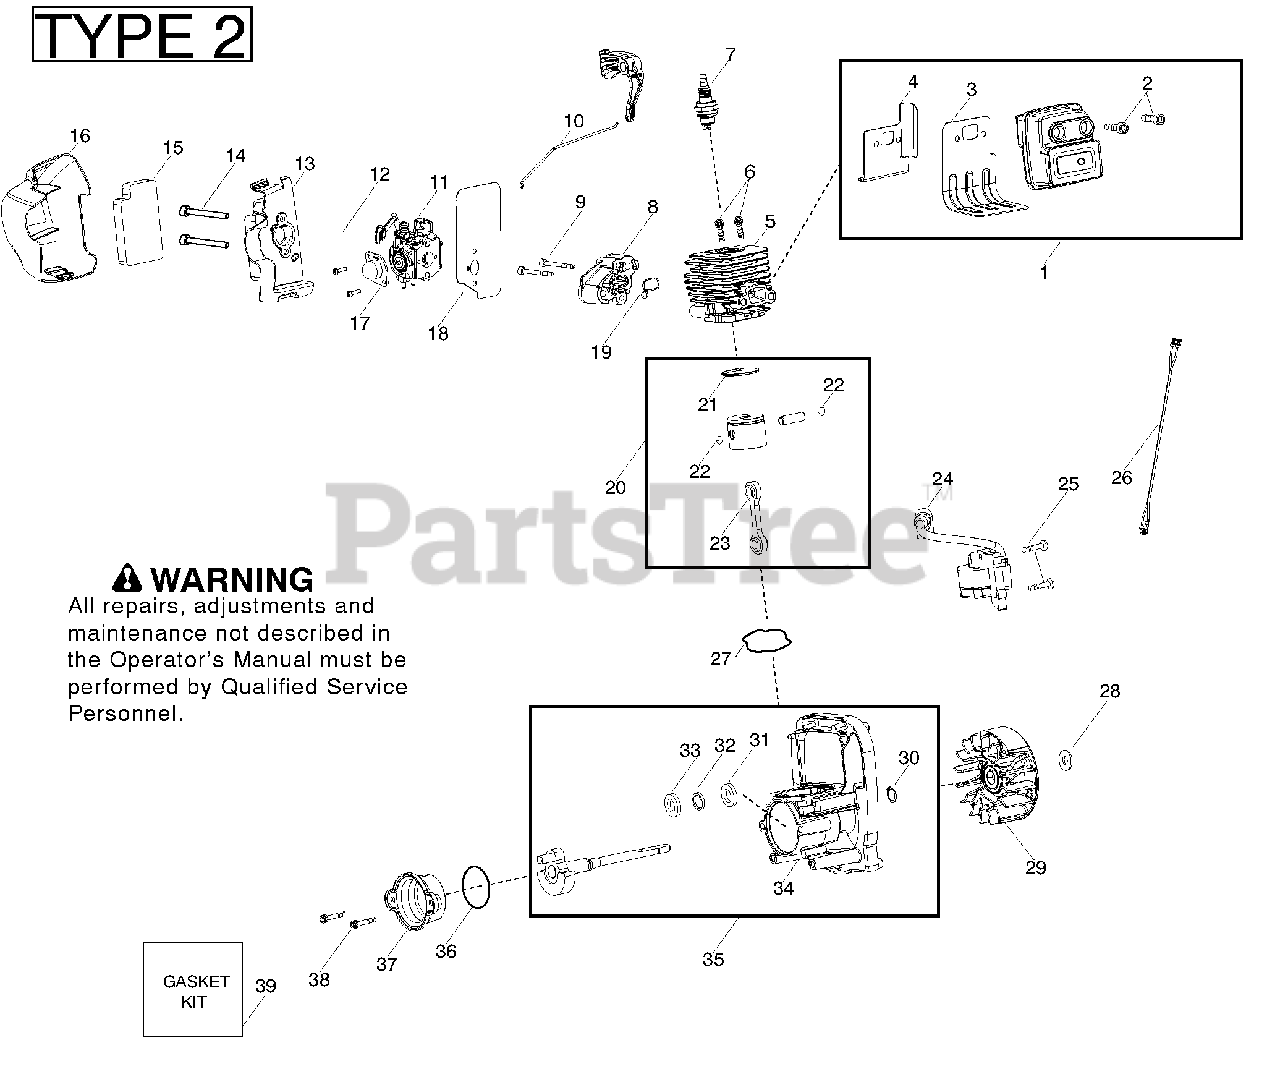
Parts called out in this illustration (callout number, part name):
1	Assy - Muffler
3	Gasket-Muffler (gasket kit)
4	Shield - Muffler Heat
5	Cylinder
7	Spark Plug (RCJ-6Y)
8	Adapter - Carb.
10	Linkage - Throttle
11	Kit - Carb. Assy (WT847)
12	Lever- Choke, (Gold)
12	Lever- Choke, (Red)
13	Base - Airbox
16	Cover - Air Box Filter
17	Bulb - Purge (walbro 188-16)
18	Gasket (Carb / Adapter) (gasket kit)
19	O-Ring (Adapter / Cylinder) (gasket kit)
20	Kit - Piston / Connecting Rod
21	Ring - Piston
22	Retainer - Wrist Pin
23	Kit - Assy. Connecting Rod
24	Module - Ignition
26	Assy - Wire Harness
27	O-Ring (Cyl/Crankcase) (gasket kit)
29	Assy - Flywheel
30	Retainer - Crankshaft
31	Bearing - Outer
33	Bearing - Inner
34	Assy - Crankcase
35	Assy - Crankcase & Crankshaft
36	O-Ring (Rear Plug) (gasket kit)
37	Assy - Rear Plug
39	Kit - Gasket
